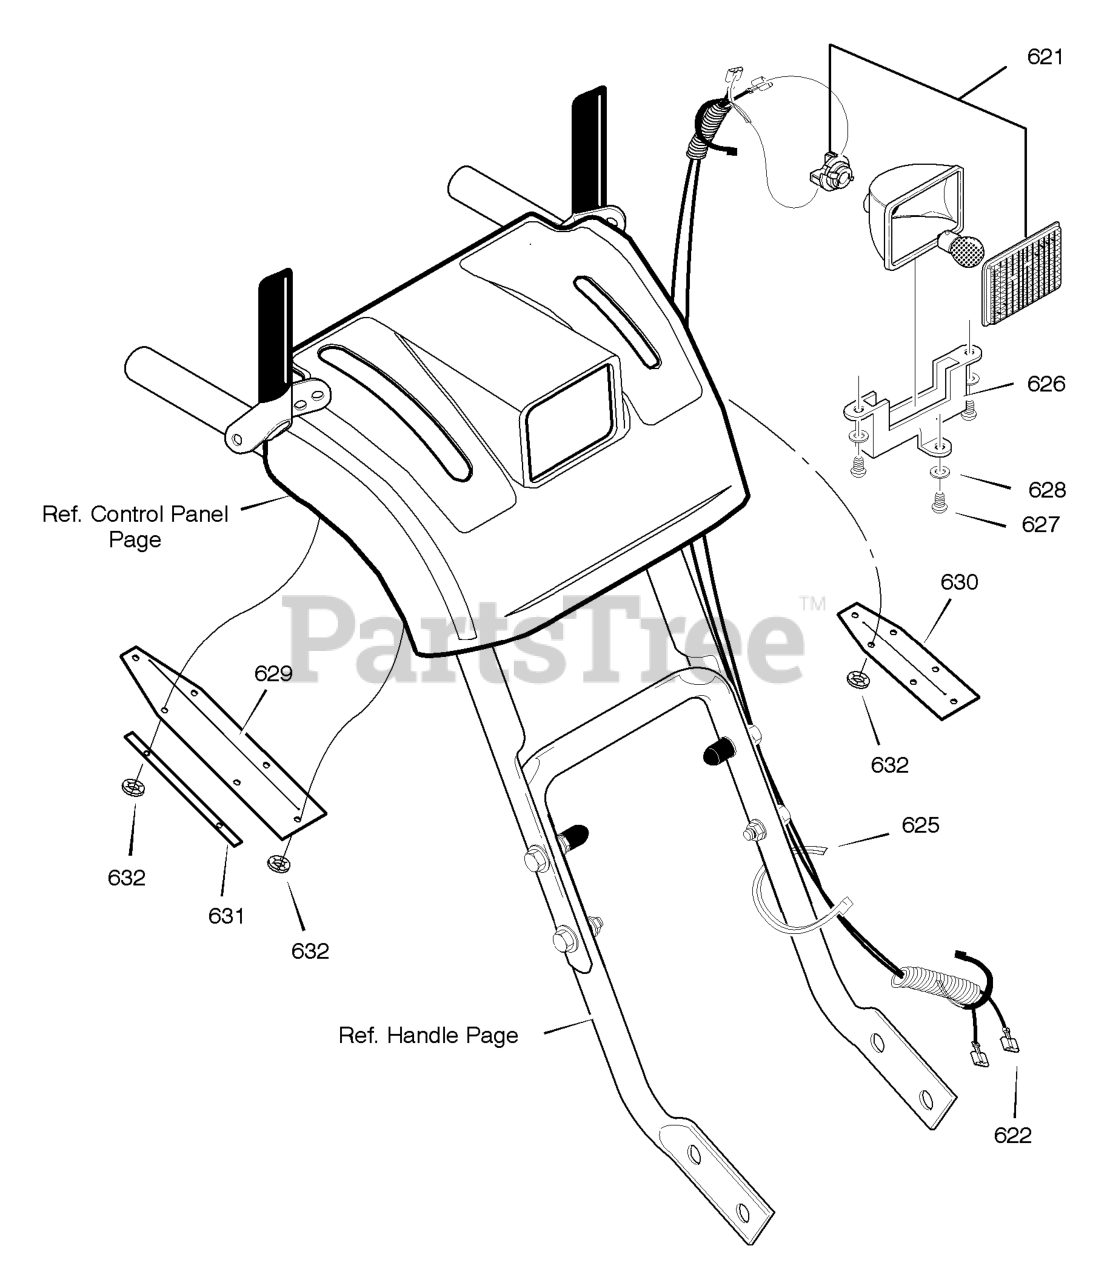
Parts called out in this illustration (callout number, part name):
621	LIGHT, HALOGEN *
622	HARNESS, HALOGEN WIRE
625	TIE, CABLE
626	BRACKET, LIGHT
627	SCREW #8 X 0.50
628	WASHER, FLAT
632	NUT, PUSH
